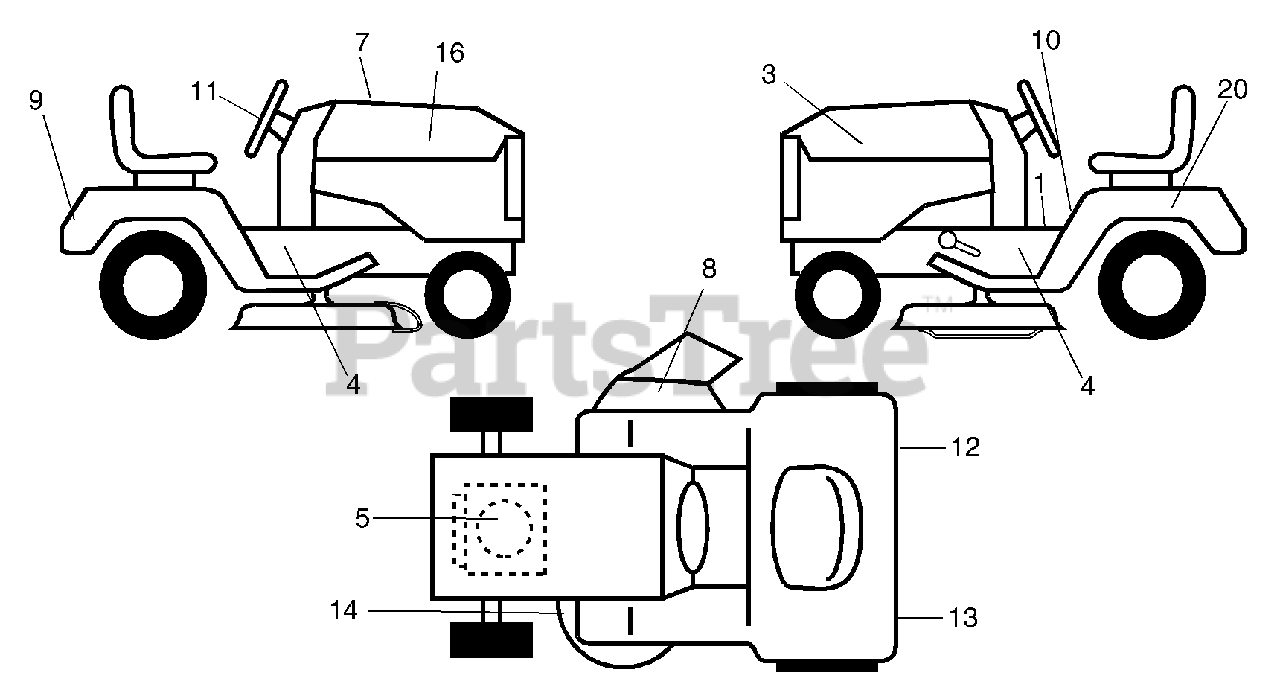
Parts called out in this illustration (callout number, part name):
1	Decal Oper
3	Decal Hood LH
4	Decal Chassis
5	Decal HP Engine
7	Decal Replacement Parts
8	Decal Deck "B" 42"
9	Decal Fender Logo
10	Decal Fender Danger
11	Decal Ins Strg Whl
12	Decal Fend Reflector Rh
13	Decal Fend Reflector Lh
14	Decal V-Belt Schematic
16	Decal Hood Rh
20	Decal Bat Dan/Psn
20	Decal By Pass Lt Hydro
